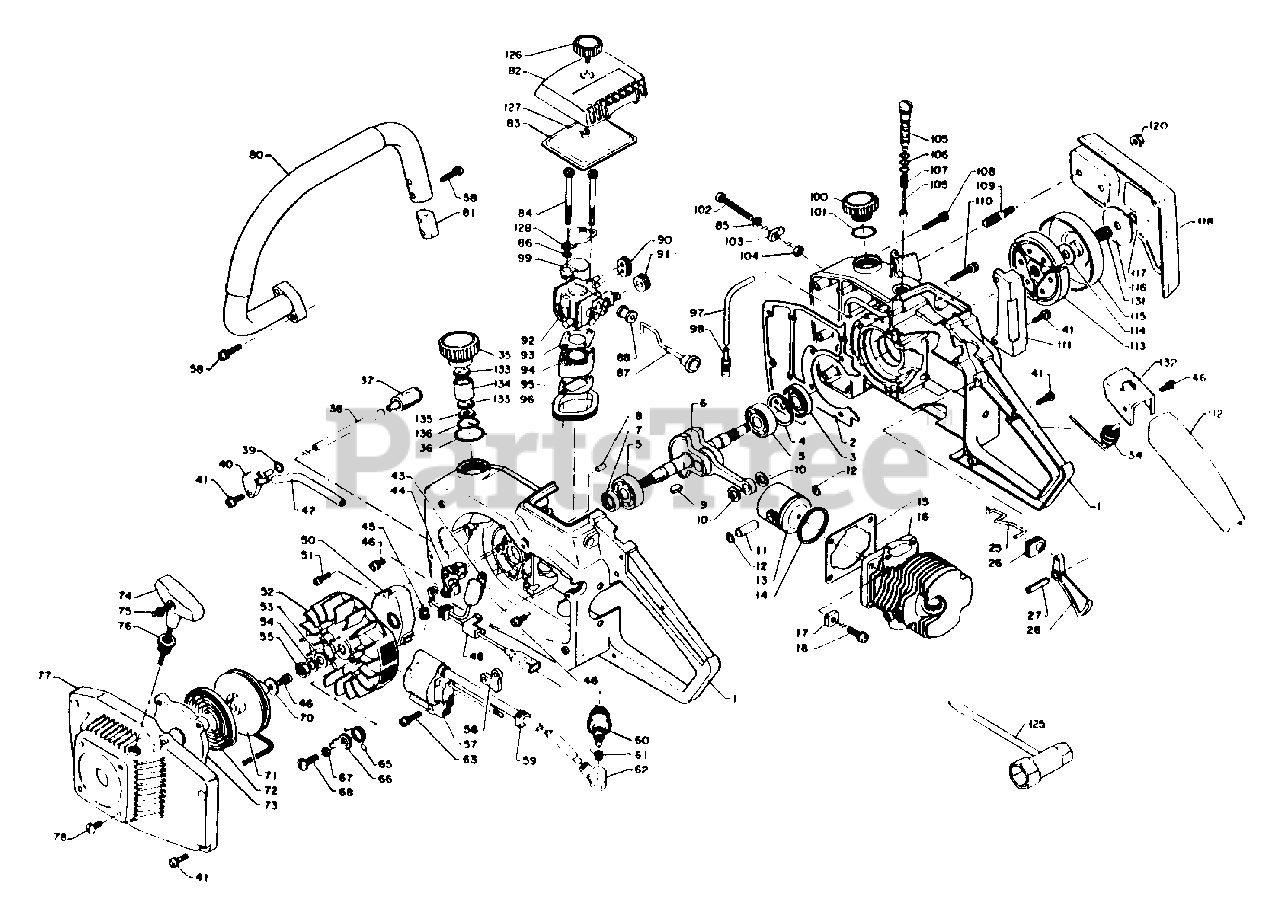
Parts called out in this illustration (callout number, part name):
1	CRANKCASE KIT
2	GASKET, CRANKCASE
3	SEAL, OIL
4	RING, RETAINING - 32
5	BEARING, BALL - 6201
6	CRANKSHAFT ASSY
7	SEAL, OIL
8	PIN - LOCATING
10	SPACER, PISTON
11	PIN, PISTON
12	RING, RETAINING
13	PISTON
14	RING, PISTON
15	GASKET, CYLINDER
16	CYLINDER
17	NUT
18	SCREW - 5X22
25	ROD, THROTTLE
26	GROMMET
27	PIN - SPRING -- 5X25
28	TRIGGER, THROTTLE
34	IGNITION SWITCH ASSY
35	CAP ASSY
36	O-RING - 22
37	FILTER, FUEL
38	PIPE - FUEL
39	O-RING - 7
40	CONNECTOR, PIPE
41	SCREW - 4X14
42	PIPE, FUEL - OUTER
43	CONDENSER
44	CONTACT POINT SET
45	PAD, OIL
46	SCREW - 4X10
48	CLAMP
50	COVER, BREAKER
51	SCREW - 3X16
52	FLYWHEEL
53	WASHER - 8
54	LOCKWASHER - 8
56	SPACER
57	COIL, IGNITION
58	SCREW - 4X20
59	BUSHING
60	SPARK PLUG -- BM-6A
61	TERMINAL, SPARK PLUG CAP
62	CAP, SPARK PLUG
65	SPRING, RETURN
66	PAWL, STARTER
68	SCREW
71	REEL, ROPE
72	SPRING, REWIND
73	CASE, STARTER
74	GRIP, STARTER
75	ROPE, STARTER - 3.5X850
76	GUIDE, ROPE
77	CASE, STARTER
78	SCREW
80	HANDLE - FRONT
81	INSERT
82	COVER, AIR FILTER
83	FILTER, AIR
84	SCREW - 5X55
85	WASHER - 5
86	WASHER - 5
87	ROD, CHOKE
92	CARBURETOR
93	GASKET, INTAKE
94	INSULATOR, INTAKE
95	GASKET, INTAKE
96	SEAL, DUST
97	PIPE - OIL
98	FILTER, OIL
99	SHUTTER, CHOKE
100	CAP, OIL TANK
101	O-RING - 16
102	SCREW - 5X40
103	TENSIONER, CHAIN
104	LOCKNUT - 5
105	AUTO-OILER ASSY
106	O-RING - 5
108	SCREW - 4X25
109	STUD, GUIDE BAR
110	SCREW - 4X25
111	SEAL, DUST
112	GRIP, HANDLE - REAR
113	CLUTCH ASSY
114	WASHER, CLUTCH
115	CASE, CLUTCH
116	WASHER, CLUTCH
117	RING, RETAINING
118	GUARD, SPROCKET
120	NUT - FLANGE
125	T-WRENCH - 10X19mm
126	THUMBSCREW
127	RING, RETAINING - 3
128	BRACKET, AIR CLEANER
131	BEARING, NEEDLE
132	BRACKET, SWITCH
133	SPACER
135	FILTER
136	RING, RETAINING
